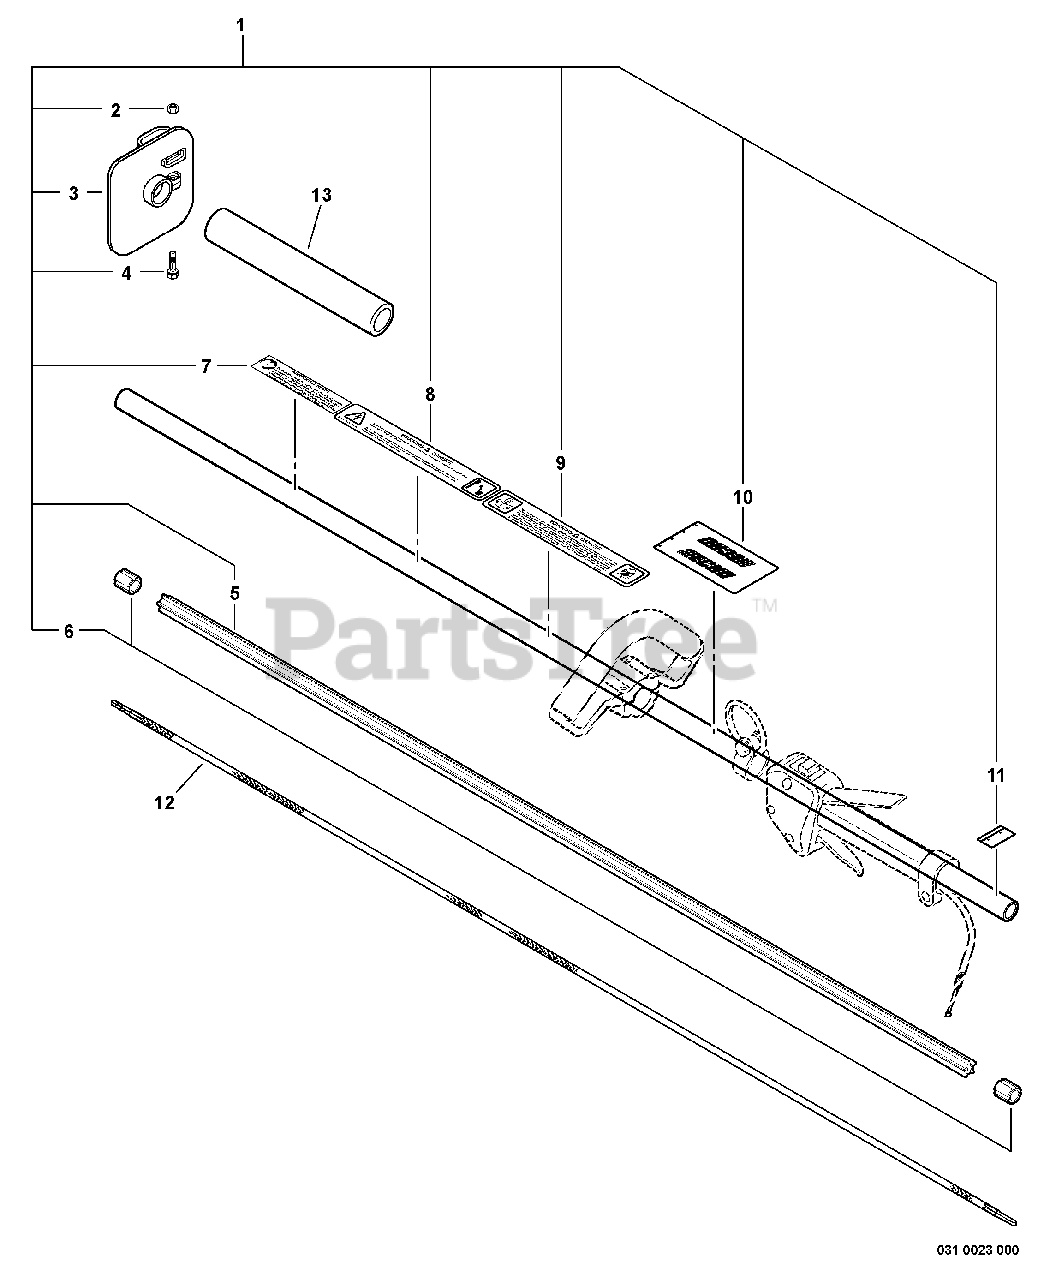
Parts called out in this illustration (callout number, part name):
1	MAIN PIPE ASSY
3	GUARD
4	BOLT - 5X20
5	LINER - FLEXIBLE
7	LABEL - CAUTION -- SPANISH
8	LABEL - CAUTION
9	LABEL - CAUTION
10	LABEL - HANDLE LOCATION
11	LABEL - ALIGNMENT
12	DRIVESHAFT - FLEXIBLE
13	GRIP, HANDLE
